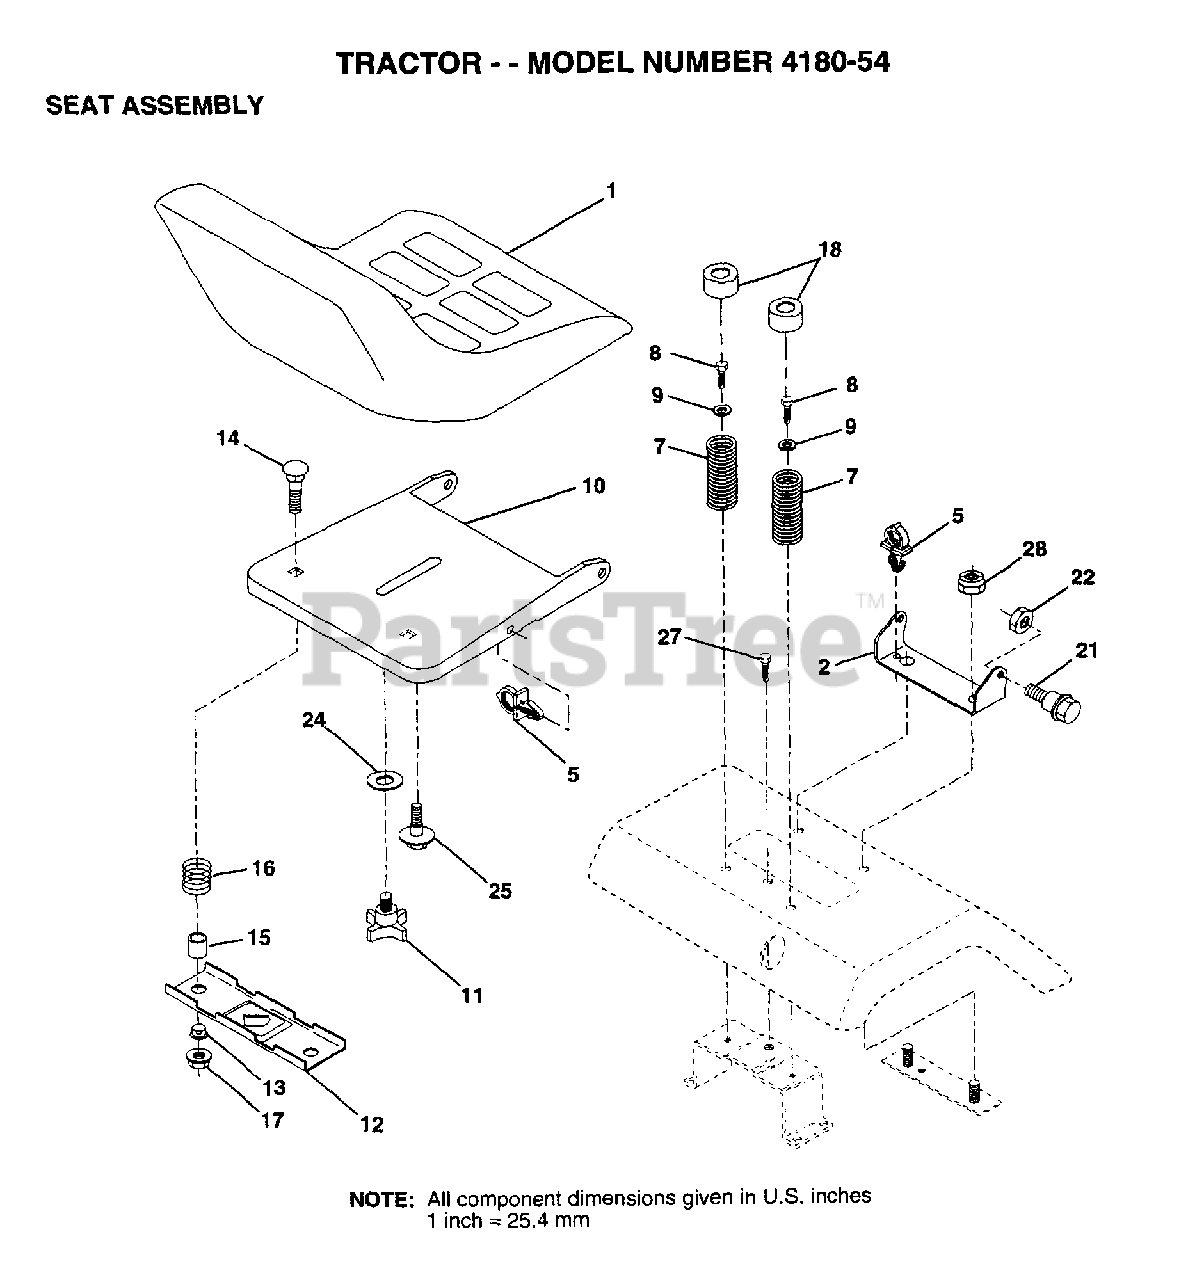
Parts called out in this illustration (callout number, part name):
2	BRACKET PVT SEAT
5	CLIP.PUSH-IN.HING
7	SPRING COMPRESSIO
8	SCREW LT
9	WASHER
11	"KNOB 1/2"" YT"
12	BRKT SWITCH
13	BUSHING
15	SPACER SPLIT
16	SPRING COMPRESSED
18	CAP SPRING
21	BOLT.SHLD.5/16-18
24	WASHER
25	"BOLT,SHOULDER"
27	SCREW LT
